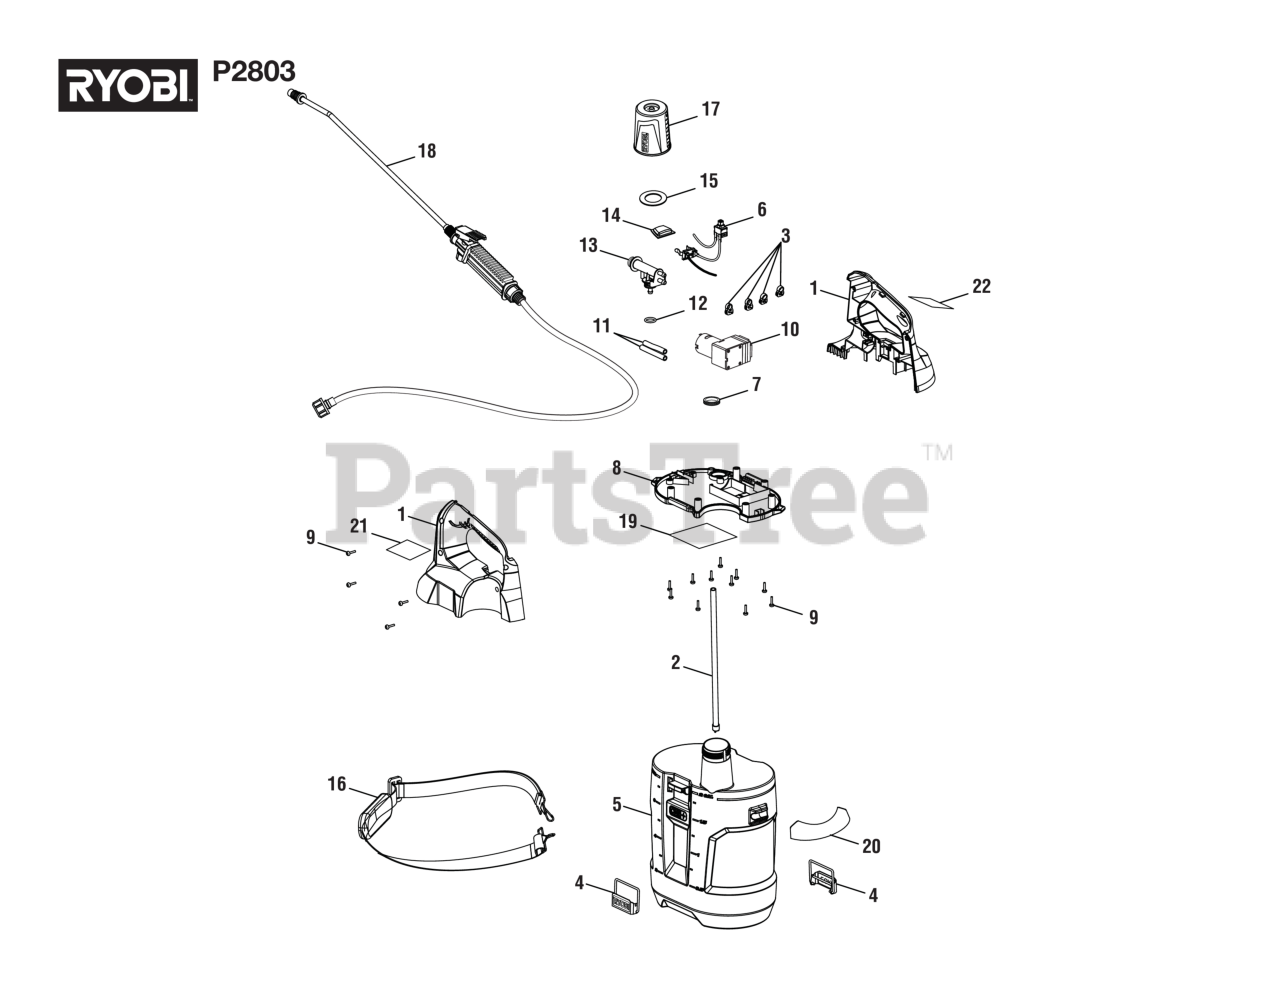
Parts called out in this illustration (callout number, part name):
1	Handle Housing Assembly
2	Tube (Long)
3	Hose Clip
5	Water Tank Assembly
6	Wiring Harness and Switch Assembly
7	Rubber Seal
8	Housing Deck Assembly
9	Screw (M4x14 mm)
10	Pump Diaphragm Assembly
11	Tube (Short)
13	Connector
14	Switch Cover
15	Rubber Seal
16	Shoulder Strap
17	Tank Cap Assembly
18	Trigger Handle Assembly
19	Data Label
20	Warning Icon Label
21	Notice Label (A)
22	Notice Label (B)
